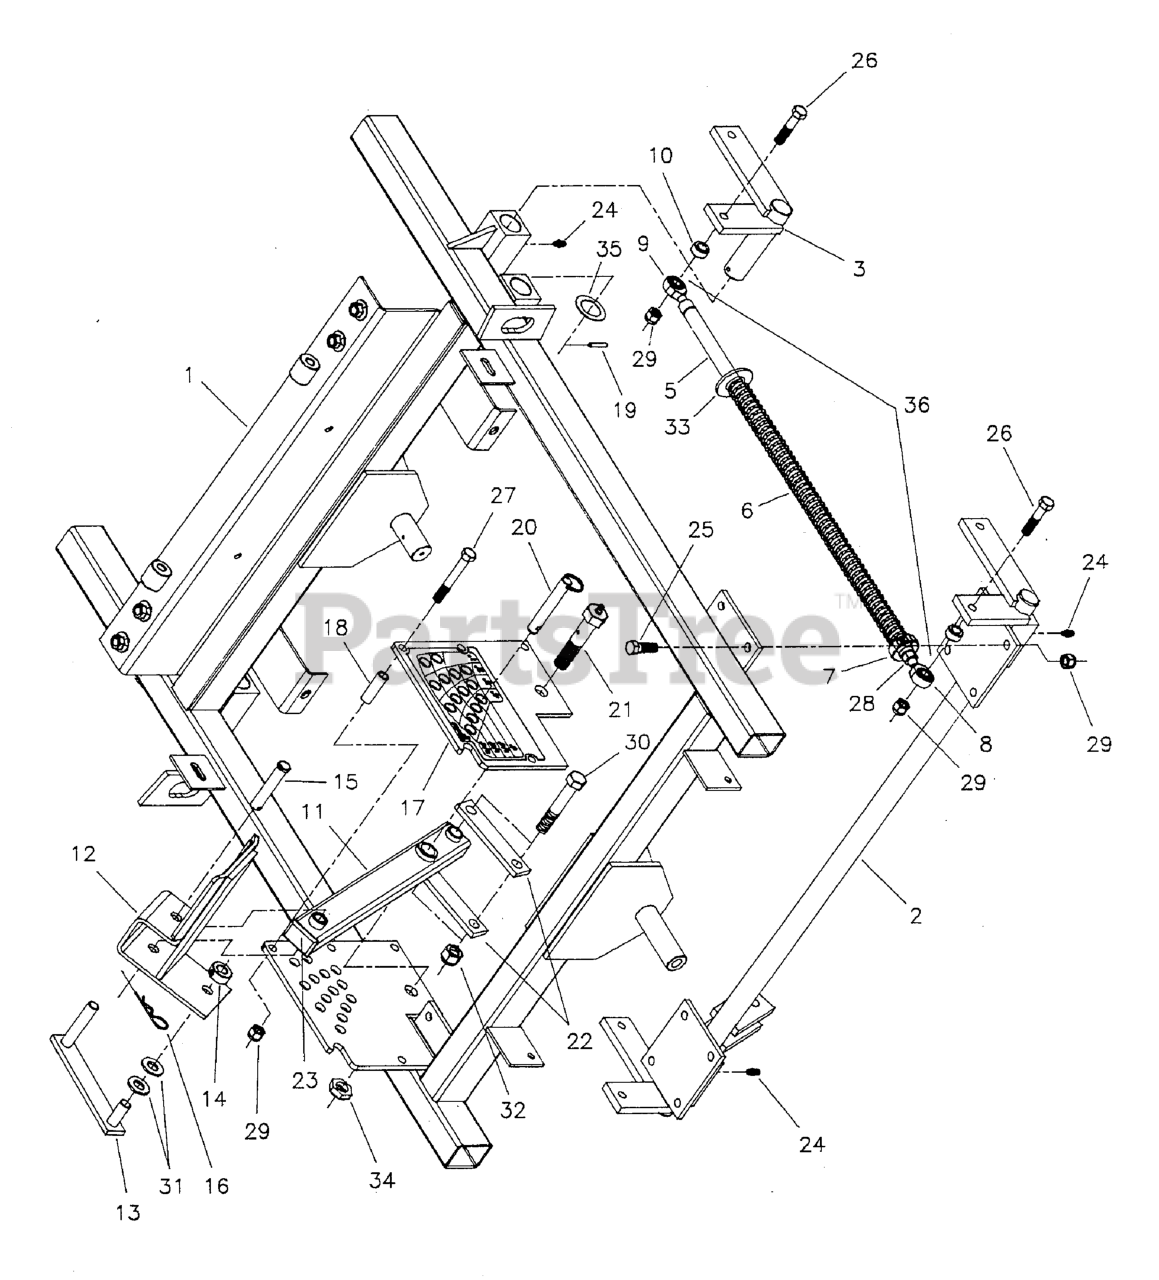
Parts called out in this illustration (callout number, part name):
1	FRAME, Main
2	SHAFT, Front Lift
3	LIFT PIVOT, Left
5	ROD, Deck Lift Spring
6	SPRING, Deck Lift
7	COLLAR, 5/8" Split
8	BALL JOINT, 3/8-24 Male
9	BALL JOINT, 3/8-24 LH Male
10	SPACER, .39 x .75 x .38
11	ARM, Deck Lift Pivot
12	FOOT PEDAL ASSEMBLY
13	DECK LIFT LOCK
14	COLLAR, 1/2" Set
15	PIN, Clevis, 1/2 x 2-1/2
16	HAIRPIN CLIP
17	LIFT PLATE ASSEMBLY
18	SPACER, .38 x .50 x 1.56
19	PIN, Roll, 3/16 x 1
20	PIN, 1/2 x 3
21	LIFT PIVOT BOLT
22	DECK LIFT LINK
24	GREASE FITTING
25	BOLT, 3/8-16 X 1-1/4" GD5 CZ
26	BOLT, 3/8-16 X 1-3/4" GD5 CZ
27	BOLT, 3/8-16 X 2-3/4" GD5 CZ
28	NUT, 3/8-24 Hex
29	NUT, 3/8-16 HEX NYLON LOCK
30	BOLT, 1/2-20 x 3
31	WASHER, 1/2 SAE
32	NUT, Hex, Nylon Lock, 1/2-20
33	WASHER, 5/8" USS Flat
34	NUT, 5/8-11 Hex Jam Nylon Lock
36	DECK LIFT SPRING ROD ASSEMBLY
